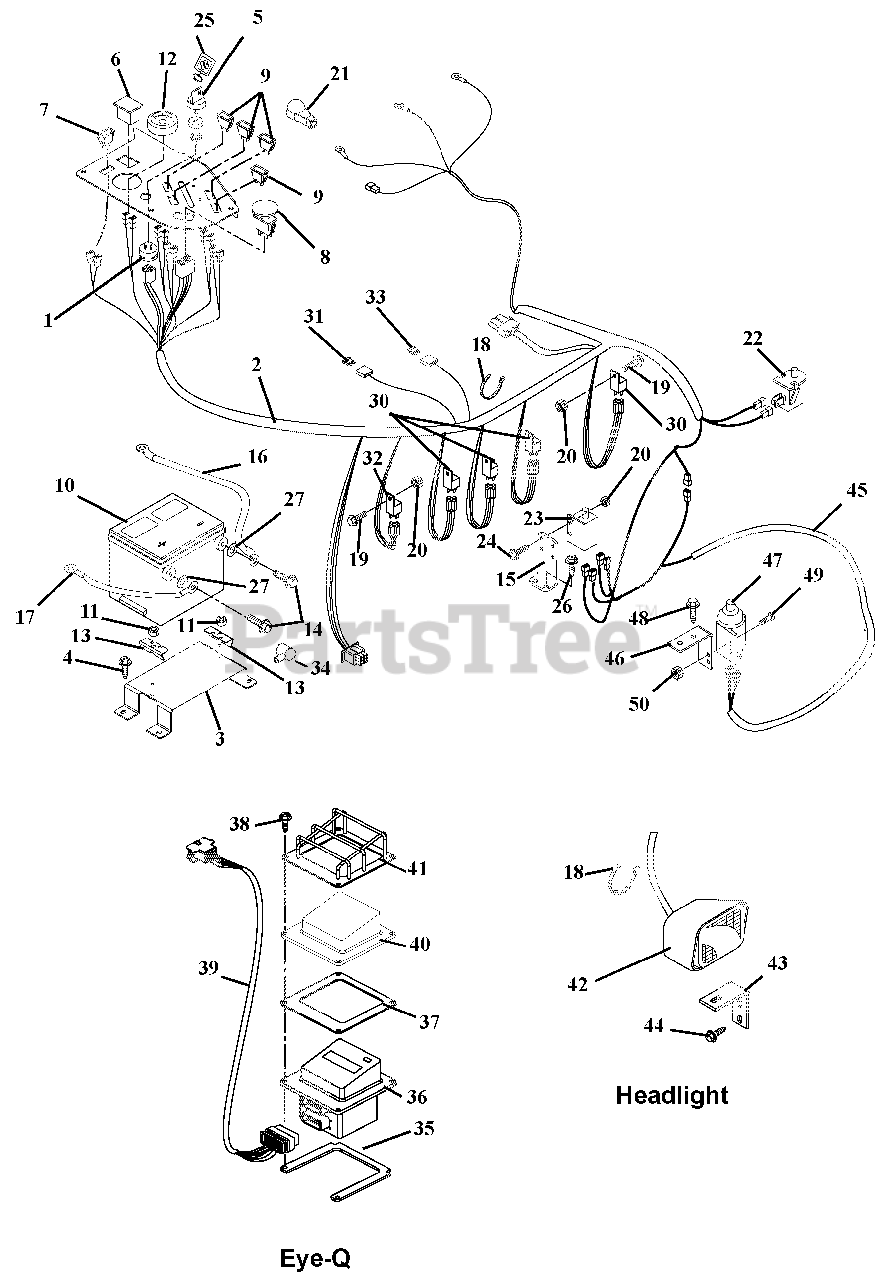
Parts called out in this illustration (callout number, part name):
1	Switch, Ignition
2	Harness, Wiring
3	Weldment, Battery Support
4	Screw-Tapping .38-16 x .75 Hex Washer Head
5	Key-with Cap
6	Hour Meter
7	Switch, Light
8	Switch-Clutch With Retainer Ring
9	Light-Indicator
10	Battery with Tube
11	Nut-Locking-Top-Flange .31-18
12	Gauge, Temperature
13	Bracket, Battery Hold-Down
14	Bolt-Hex .25-20 x .75 Grade 5
15	Mount, Safety Switch
16	Positive Cable
17	Cable, Negative Battery
18	Cable Tie
19	Screw-Machine 10-24 x .75 Hex Washer Head
20	Nut-Locking-Nylon 10-24 With Insert
21	Eyelet Terminal Boot
22	Switch, Snap Mounting (N.O.) (Included with Seat)
23	Switch-Single Pole
24	Screw-Machine 10-24 x .75 Hex Washer Head
25	Key Chain
26	Screw-Tapping .25-20 x .50 Hex Washer Head
27	Washer-Flat-Steel .406 x 1.00 x ..083
28	Fuse, ATO 15 Amp
29	Diode, Connector Shell
30	Relay (Included with Harness)
31	Fuse, ATO 30 Amp (Included with Harness)
32	Pre-Heat Timer (Included with Engine)
33	Fuse, ATO 60 Amp (Included with Harness)
34	Boot, Eyelet Terminal
35	Spacer, Enclosure Mounting (Bottom)
36	Assembly, Eye-Q
37	Gasket, Eye-Q
38	Screw, Machine 10-24 x 1.0 Slotted Pan Black
39	Harness Jumper (Eye-Q)
40	Guard, Element
41	Guard, Vinyl Eye-Q
42	Headlight
43	Bracket, Headlight Mounting
44	Screw, Tapping, .38-16 x .50 Hex Washer Head
45	Harness, Wire Adapter, CE
46	Switch, Mount
47	Switch, Single Pole (N.O.) with Cover
48	Screw,Tapping .31-18 x .50 Hex Washer Head
49	Screw, Machine 10-24 x .75 Hex Washer Head
50	Nut, Locking, Nylon 10-24 with Insert
